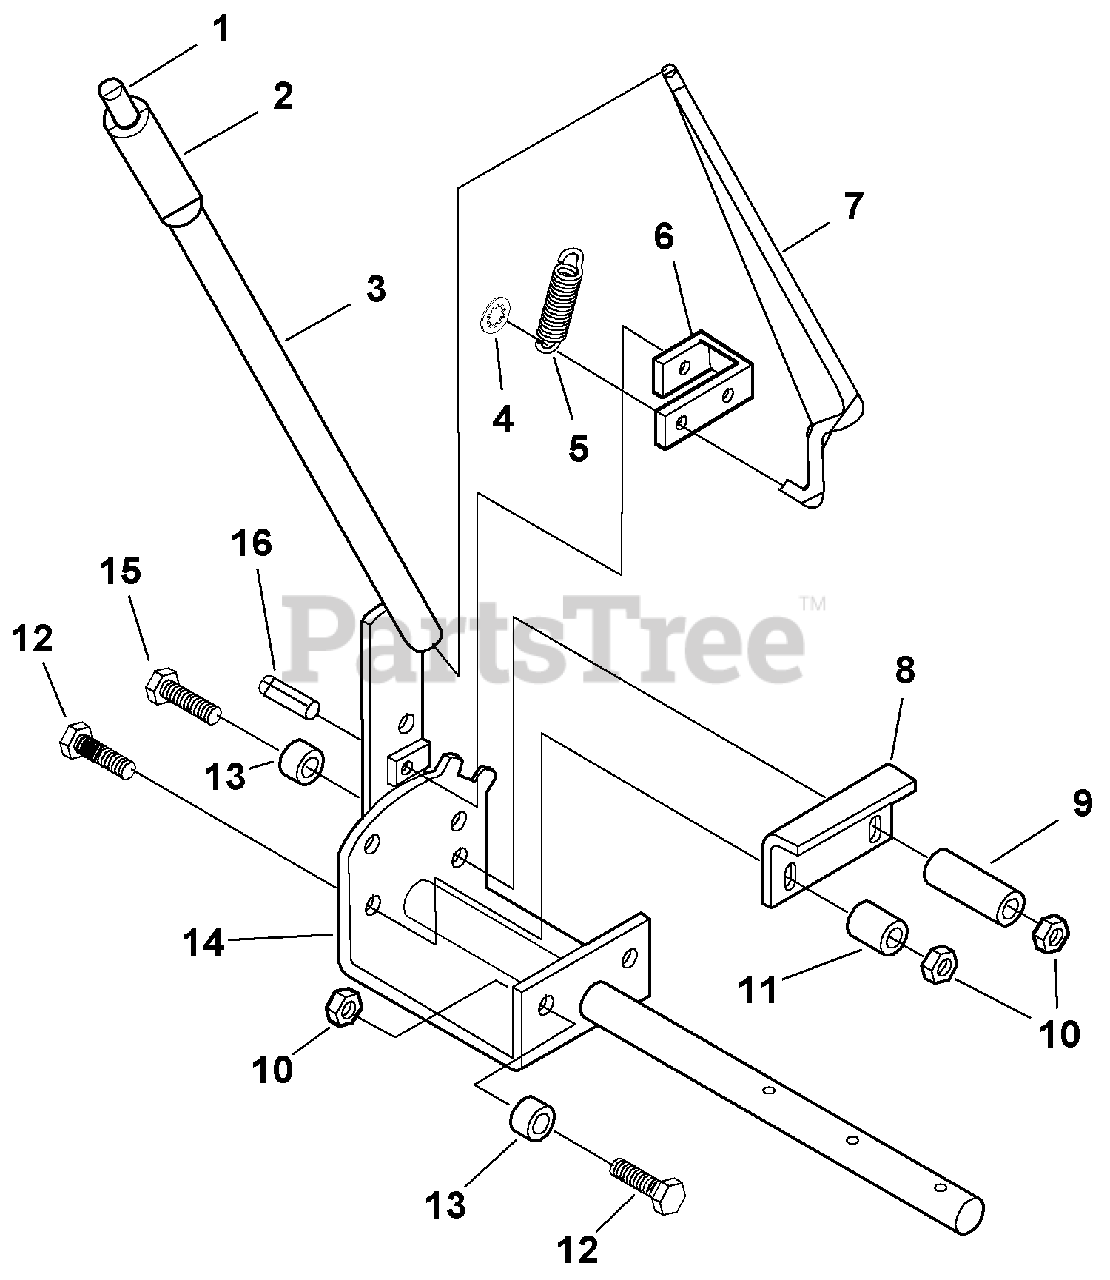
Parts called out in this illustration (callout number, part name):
3	LEVER ASSEMBLY
4	PUSH NUT, 5/16
6	LATCH, Lift Lever
8	BRACKET
10	LOCKNUT, 5/16-18
12	CAPSCREW, Hex Head 5/16-18 x 1-1/4
14	QUADRANT, Lift
15	CAPSCREW, Hex Head, 3/8-18 x 2-1/2
16	ROLL PIN, 3/8 x 1
